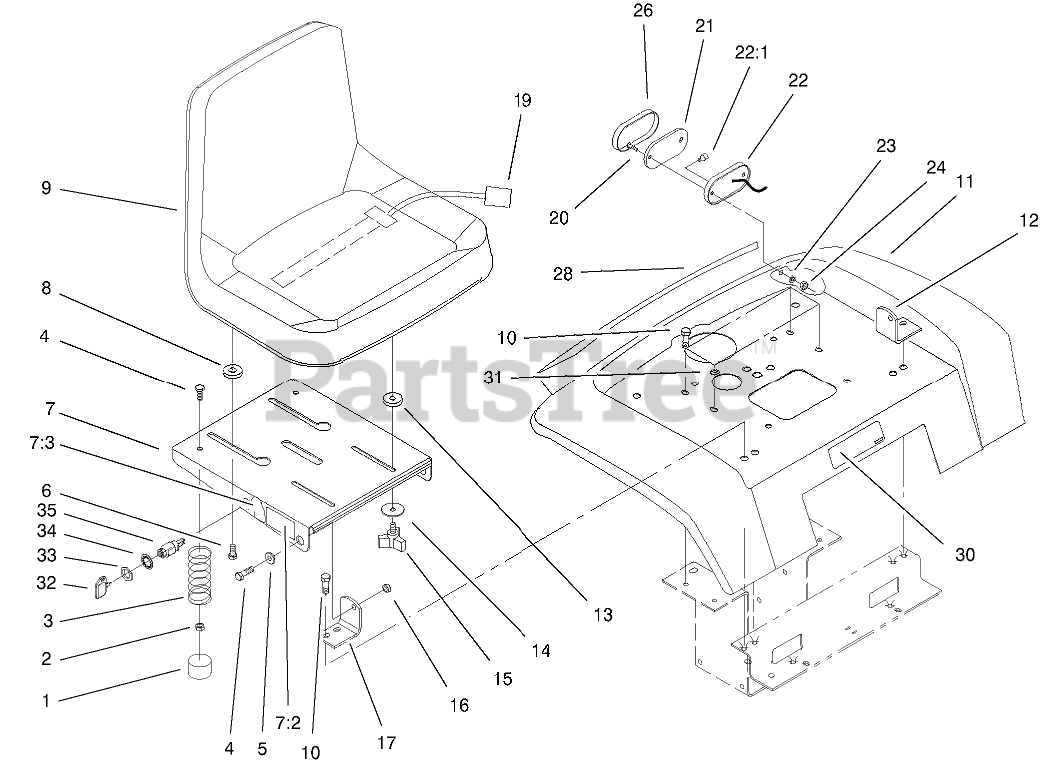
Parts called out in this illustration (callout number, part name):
1	CAP-PROTECTOR
2	NUT-LOCK, NI
3	SPRING-COMPRESSION
4	SCREW-HH
5	BUSHING
6	BOLT-SHOULDER
7	SUPPORT-SEAT
7:2	DECAL-DANGER
7:3	DECAL
8	SPACER-NYLON
9	SEAT-V-511
10	SCREW-HWHTF
12	BRACKET-PIVOT, LH
13	SPACER-NYLON
14	WASHER
16	NUT-LOCK, NI
17	BRACKET-PIVOT, RH
19	SWITCH-SEAT
20	SCREW-PPH
21	Reflector (only on: 73429)
22	Base-Taillight (only on: 73449)
22:1	Bulb (only on: 73449)
23	Washer-Lock/Int (only on: 73449)
24	NUT-LOCK, NI
26	Lens-Tail Light (only on: 73449)
28	DECAL - REAR FENDER
30	DECAL - USA
31	Washer-Lock/Ext (only on: 73449)
32	KEY-IGNITION
33	NUT-HH
34	WASHER-TOOTH, INTERNAL
35	STARTER SWITCH ASM
